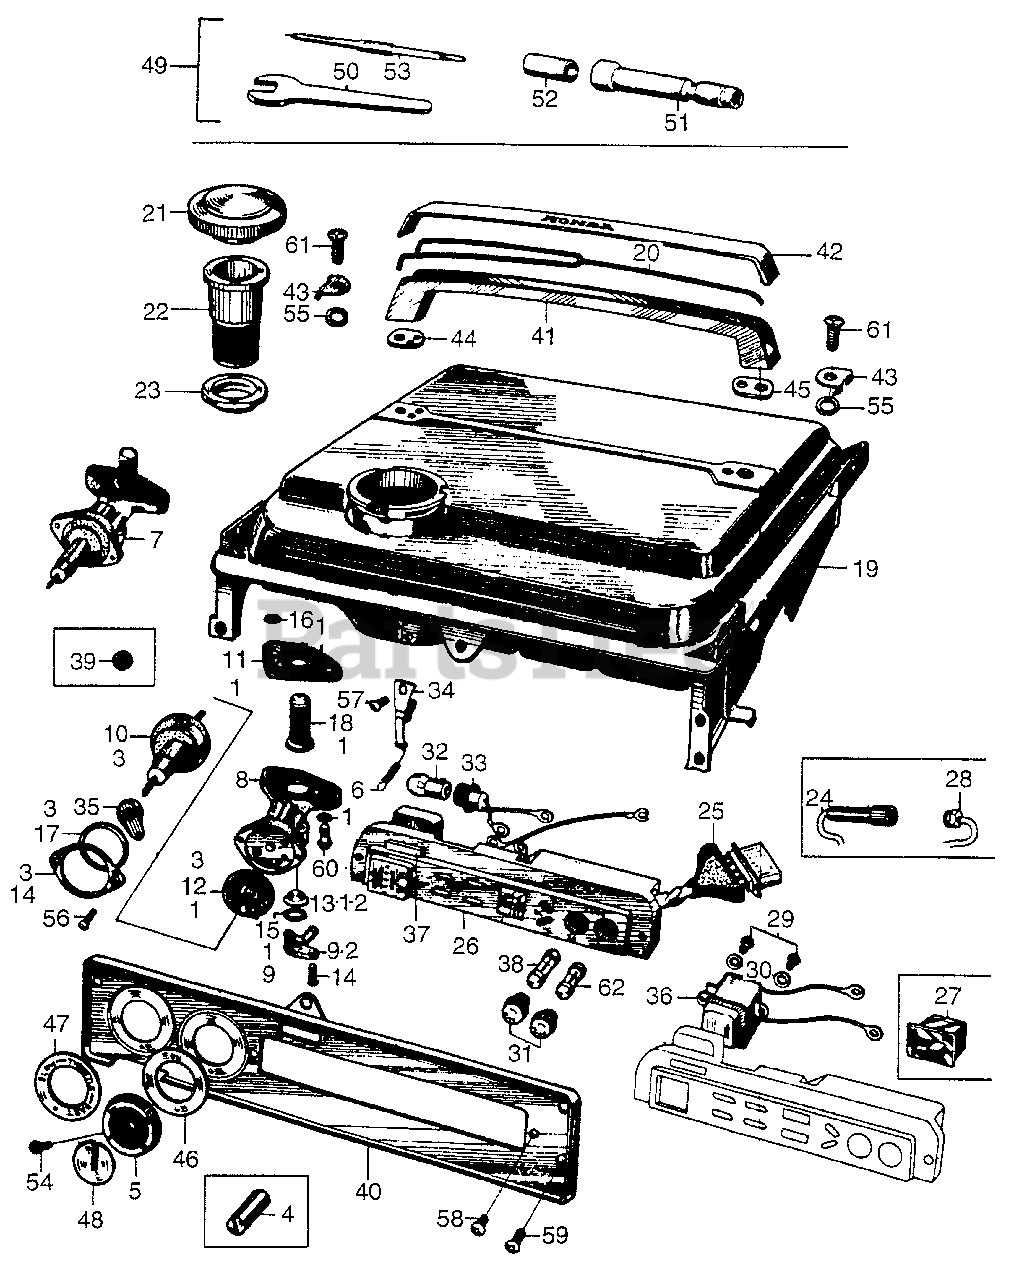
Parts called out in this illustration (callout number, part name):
5	KNOB, CONTROL
6	GASKET, STRAINER SETTING (NOT AVAILABLE)
7	PETCOCK ASSY.
8	BODY, PETCOCK
9	CAP, PETCOCK (NOT AVAILABLE)
10	LEVER, VALVE (NOT AVAILABLE)
11	GASKET A, PETCOCK (NOT AVAILABLE)
12	GASKET, VALVE
13	FILTER, CHECK (NOT AVAILABLE)
14	PLATE, LEVER
15	GASKET, O-TYPE (NOT AVAILABLE)
16	COLLAR, LEVER GASKET
17	SPRING, PETCOCK LEVER (NOT AVAILABLE)
18	FILTER, CHECK (NOT AVAILABLE)
19	TANK, FUEL *NH2M* (METALLIC SILVER) (NOT AVAILABLE)
20	TUBE, HANDLE BREATHER (NOT AVAILABLE)
21	CAP, TANK (NOT AVAILABLE)
22	FILTER, FUEL
23	RUBBER, FILTER (NOT AVAILABLE)
25	COVER, WIRE HARNESS CONNECTOR
26	RECEPTACLE ASSY., SWITCH (NOT AVAILABLE)
26	RECEPTACLE, SWITCH
29	SCREW, PAN (3X10)
30	WASHER, SPRING (3MM)
31	HOLDER, FUSE (NOT AVAILABLE)
32	BULB, DASH (6V3W) (STANLEY)
34	SWITCH ASSY., ENGINE (NOT AVAILABLE)
35	ARM, SWITCH (NOT AVAILABLE)
36	METER, FREQUENCY
37	LENS, LAMP
38	FUSE (3A)
38	FUSE ASSY., SPARE
39	RUBBER, GUIDE (NOT AVAILABLE)
40	PANEL, FR.
40	PANEL, FR. *NH2M* (METALLIC SILVER)
41	HANDLE, CARRY
42	COVER, HANDLE (NOT AVAILABLE)
43	HOOK, HANDLE COVER
44	GASKET A, HANDLE (NOT AVAILABLE)
45	GASKET B, HANDLE (NOT AVAILABLE)
46	MARK, VALVE KNOB (NOT AVAILABLE)
47	MARK, THROTTLE KNOB (NOT AVAILABLE)
48	MARK, CONTROL KNOB
50	WRENCH (8MM) (OPEN END) (NOT AVAILABLE)
51	WRENCH, SPARK PLUG (NOT AVAILABLE)
52	RUBBER, FRICTION (NOT AVAILABLE)
53	SCREWDRIVER
54	SCREW, STOP (3MM)
55	O-RING (5X1.5) (NOT AVAILABLE)
56	SCREW, PAN (3X6) (NOT AVAILABLE)
57	SCREW, PAN (3X6)
58	SCREW, PAN (4X8)
59	SCREW, PAN (5X10)
60	SCREW, PAN (6X16)
61	SCREW, PAN (6X20)
62	FUSE A (10A)
